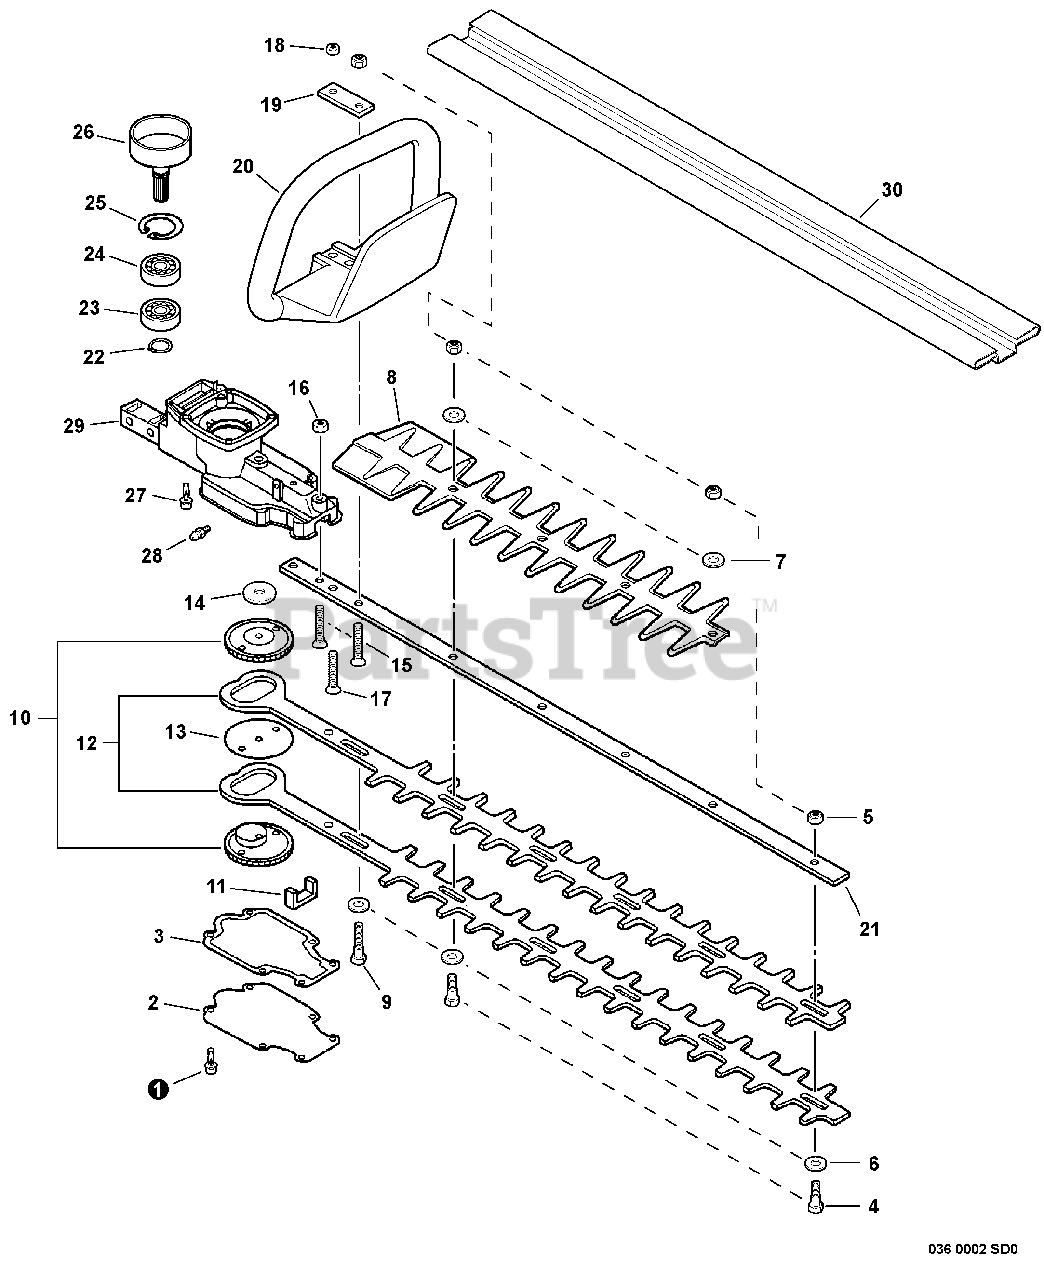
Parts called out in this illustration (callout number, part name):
1	BOLT 4×12
2	COVER, GEAR CASE
3	GASKET, GEAR CASE
4	BOLT 6×18
6	WASHER 6.5×15.5×0.6
7	WASHER 6.5×15.5×0.6
8	GUARD, CUTTER BLADE
9	BOLT M6×35
10	GEAR, SPUR
12	CUTTER
13	WASHER 6.7×54×0.38
14	WASHER 6.5×30×0.2
15	SCREW 6×30
16	NUT, HEX M6
17	SCREW 5×30
18	NUT, LOCK M5
19	PLATE, EYE
20	HANDLE, SUPPORT
21	SUPPORT, BLADE
22	RING, SNAP 14
23	BEARING, BALL 6202
24	BEARING, BALL 6202
25	RING, SNAP 35
26	DRUM, CLUTCH
27	BOLT 4×16
28	FITTING, GREASE
29	CASE, GEAR
30	SCABBARD
